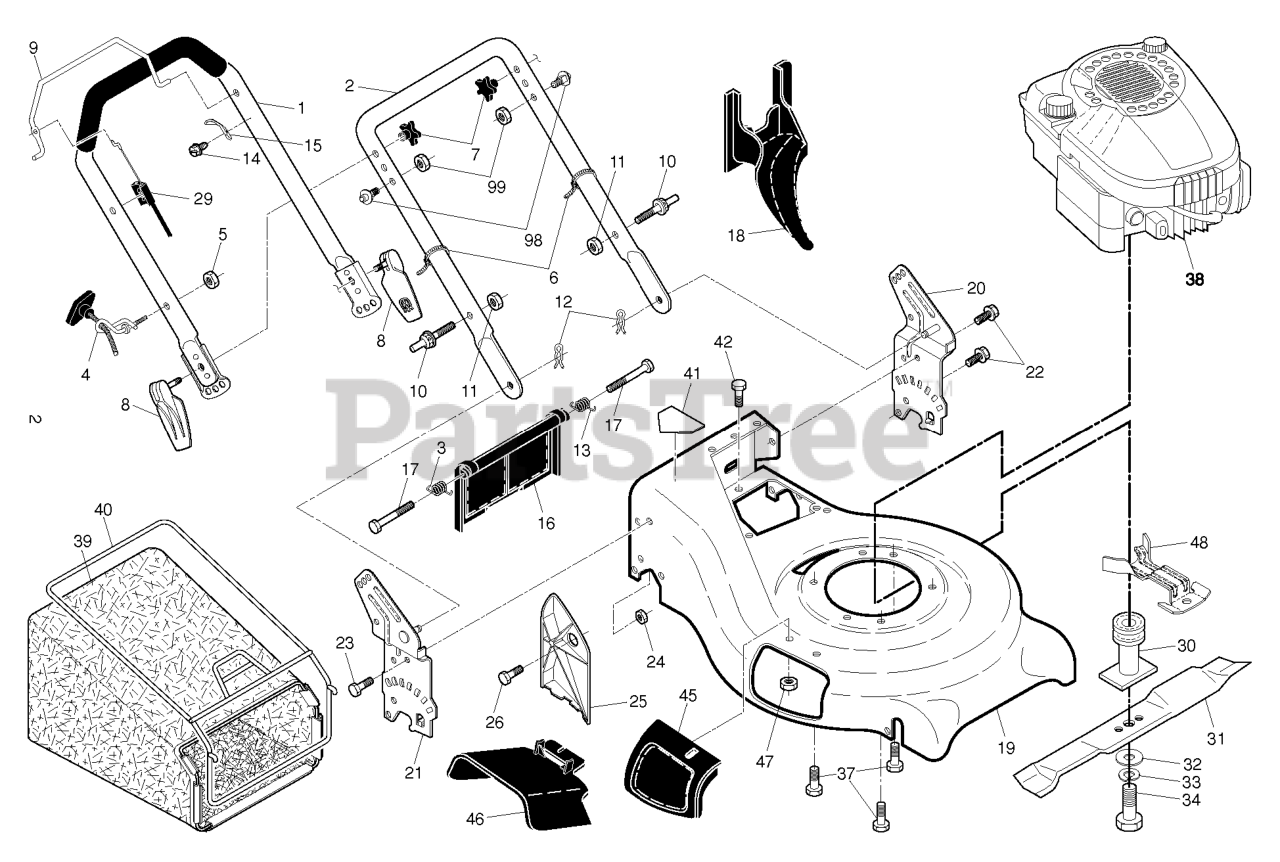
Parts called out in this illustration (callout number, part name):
1	Upper Handle
2	HANDLE.LOWER.21.PNT
3	SPRING.RH.REAR.DOOR.21.RWGD
4	RB GUIDE.ROPE.STD.BLK.ZIN WSL
5	NUT
6	TIE GUIDE
7	KNOB.HANDLE.PLASTIC.STAR.BLACK
8	QUICK.ASM.RELEASE.BLACK
9	BAIL.CONT.COMF.PUSH.ORGANGE.RH
11	NUT.LOCK.5/16-18
12	HAIRPIN COTTER
13	SPRING.LH.REAR.DOOR.21.RWGD
15	BRACKET UPSTOP
16	REAR DOOR ASSEMBLY
18	PLUG.MULCHER.RGD.21.
19	KIT.HSG.21.RGD.MC.ORG.CE
20	BRACKET.HNDL.ASM.21.RWGD.LT.OR
21	BRACKET.HNDL.ASM.21.RWGD.RT.OR
22	BOLT.HEX.HD.WASHER.5/16-18X.75
23	BOLT, HEX HEAD 5/16-18
24	NUT.71038.31-18.HEX.NYLOCK
25	CLIPPING DEFLECTOR
29	SNAP-ON.ZONE.CABLE.ASS
30	ADAPTER.BLADE/PULLEY.25M
31	BLADE.21.PUSH
32	WASHER,HARDEN
33	LOCKWASHER
34	SCREW, HEX HD 3/8-24 X 1-3/8
37	BOLT 3/8-16X1-1/8
39	GBAG.94710090.H-GRY.MS498.GEN
40	FRAME.GBAG.21.RWGD.SC
41	DECAL.INTERNATIONL.CUTFINGER
42	SCREW 14-20 X 5/8
45	MULCHER DOOR ASM.
46	DEFLECTOR, DISCHARGE
48	BRACKET.ENG/BELTKEEPER.BZP
98	STUD.QUICK.ADJUST
99	NUT.LOCK.5/16-18
